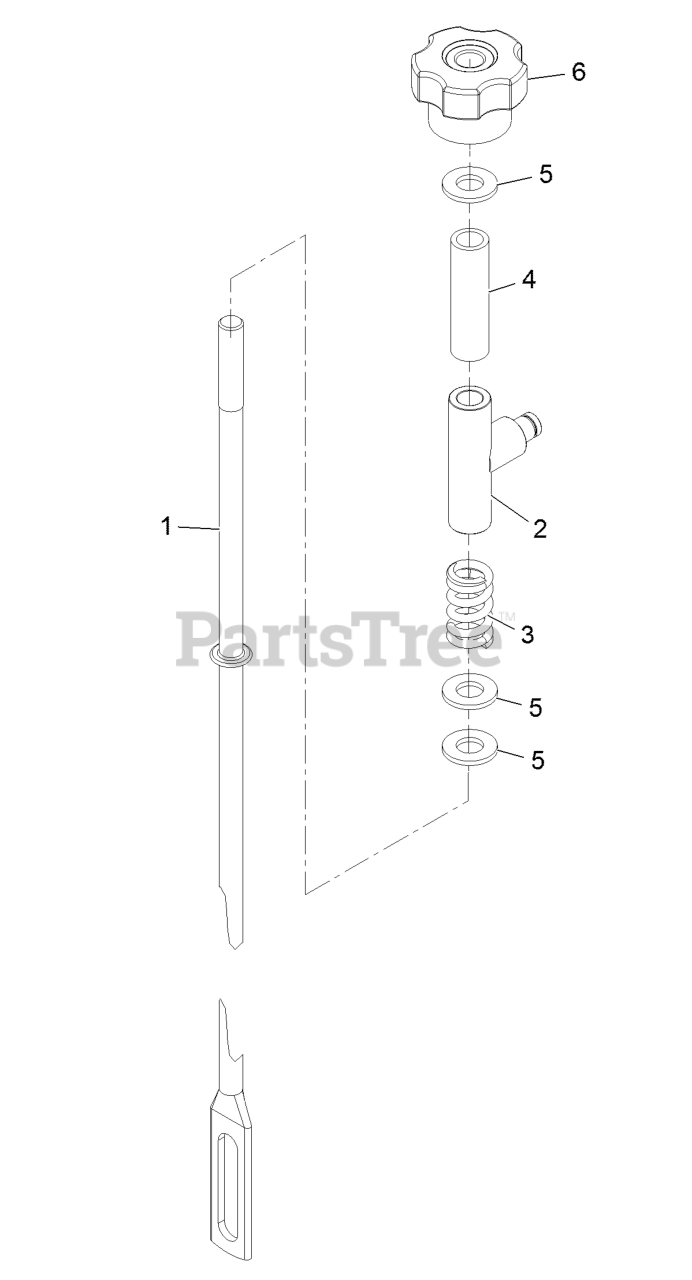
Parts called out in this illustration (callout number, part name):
1	ROD, RIGHT
3	SPRING, COMPRESSION
5	WASHER-FLAT
